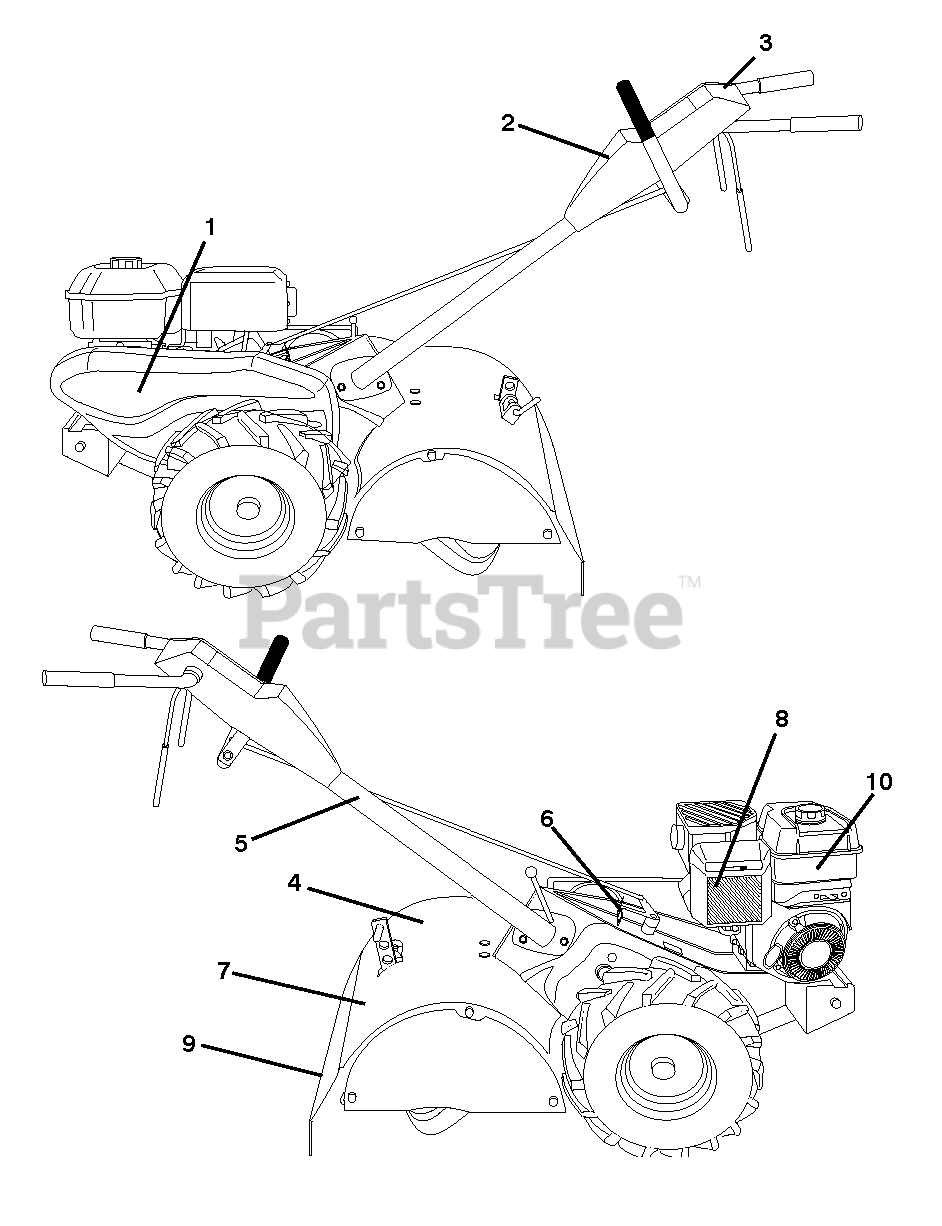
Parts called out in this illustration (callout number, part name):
1	RP.DECAL.BADGE.170MM.TEXTLOGO
2	DECAL, HUSQVARNA,CONTROL PANEL
3	DECAL, CONTROL TINE
4	DECAL.SHIELD
5	DECAL TI (2 2)
6	DECAL.SHIFT.INDICATOR.TILLER
7	DECAL.WARNING.SHLD.ENG/FR
8	DECAL.B&S.900.A/S.C (279005)
9	DECAL TI
10	DECAL.B&S.900.TANK.REF.276991
